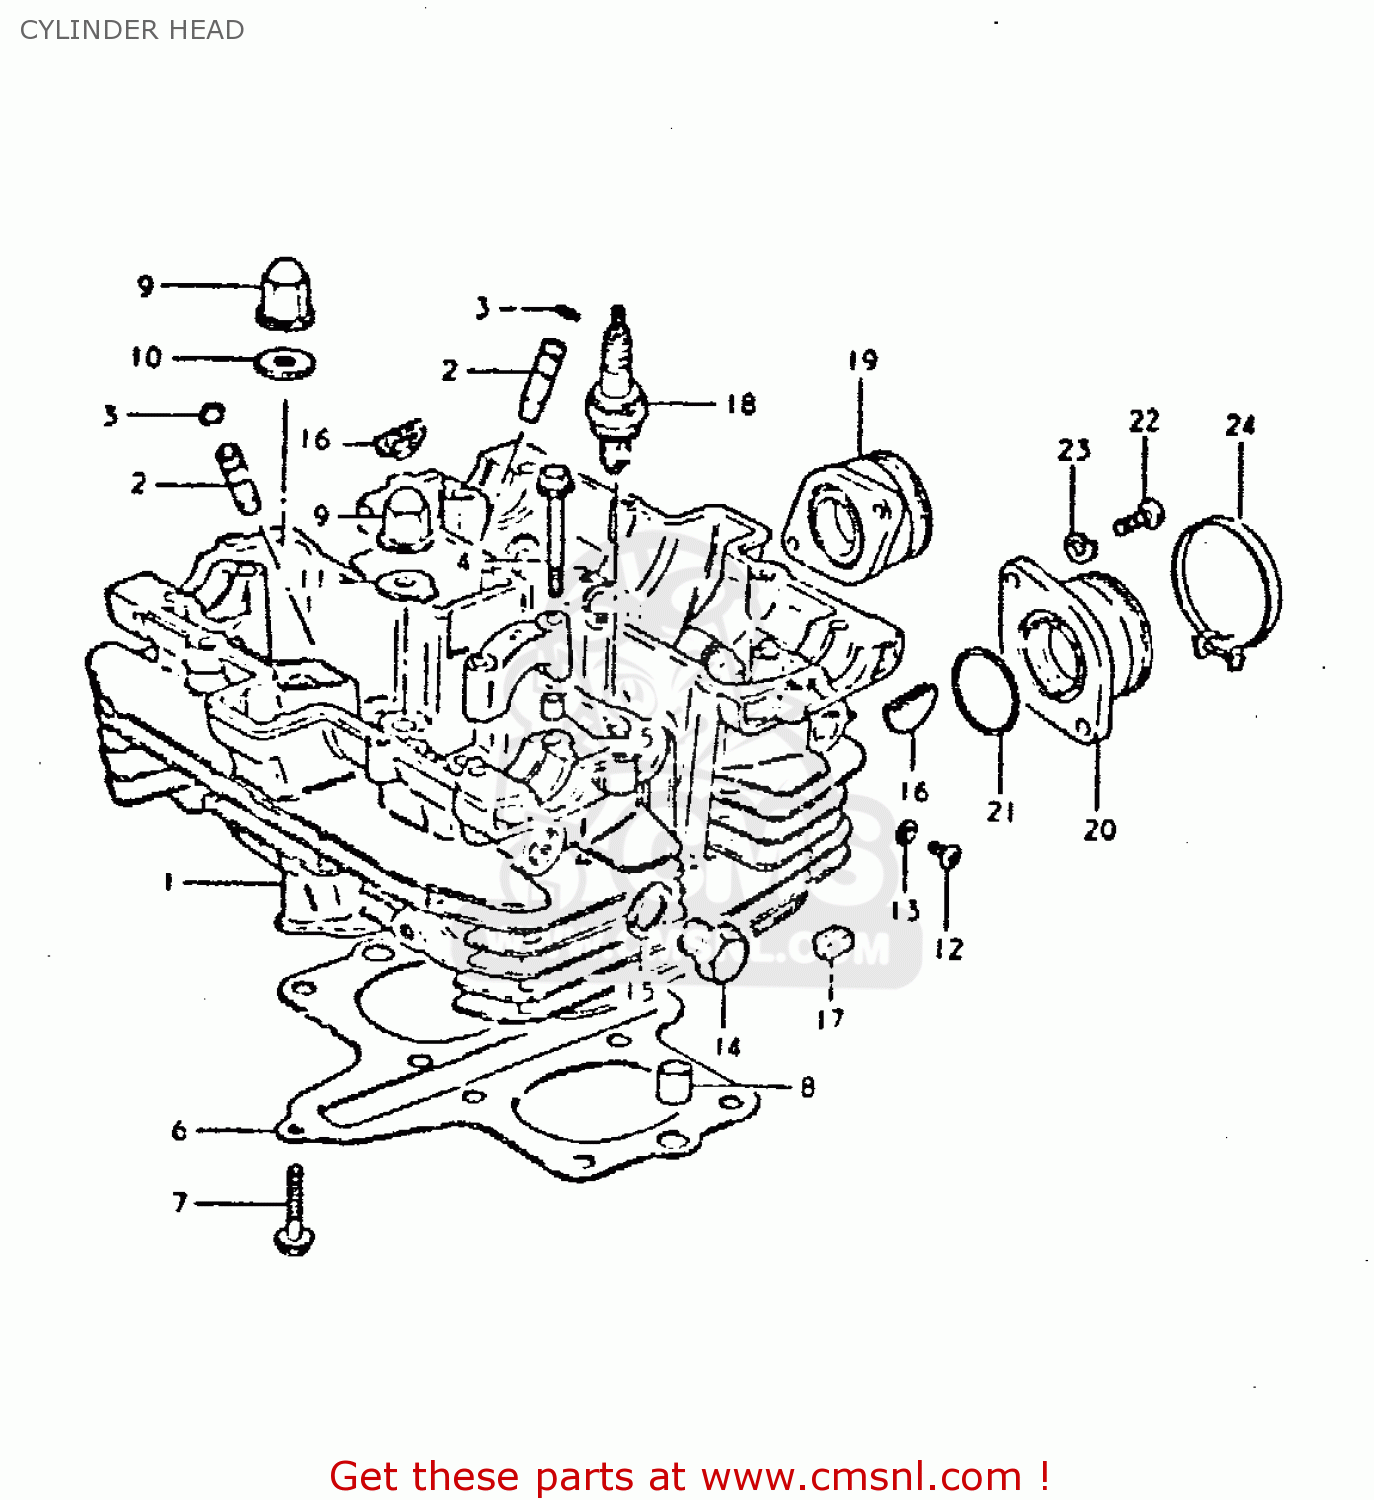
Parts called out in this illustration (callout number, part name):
1	CYLINDER HEAD SET
2	GUIDE,INTAKE VALVE
3	RING,SNAP
4	BOLT(6X39)
5	PIN(6.2X8X11)
6	GASKET (MCA)
7	BOLT
8	PIN
9	NUT
10	GASKET (NAS)
11	GASKET(10X22X2.3) (NAS)
12	SCREW
13	GASKET(5.3X9.3X1.2) (NAS)
14	PLUG (14X12)
15	GASKET(14X19.2X2) (NAS)
16	PLUG
17	PAD
18	SPARK PLUG DR8ES-L
19	PIPE,INTAKE,R
20	PIPE,INTAKE,L
21	O-RING
22	SCREW
23	LOCK WASHER
24	CLAMP
